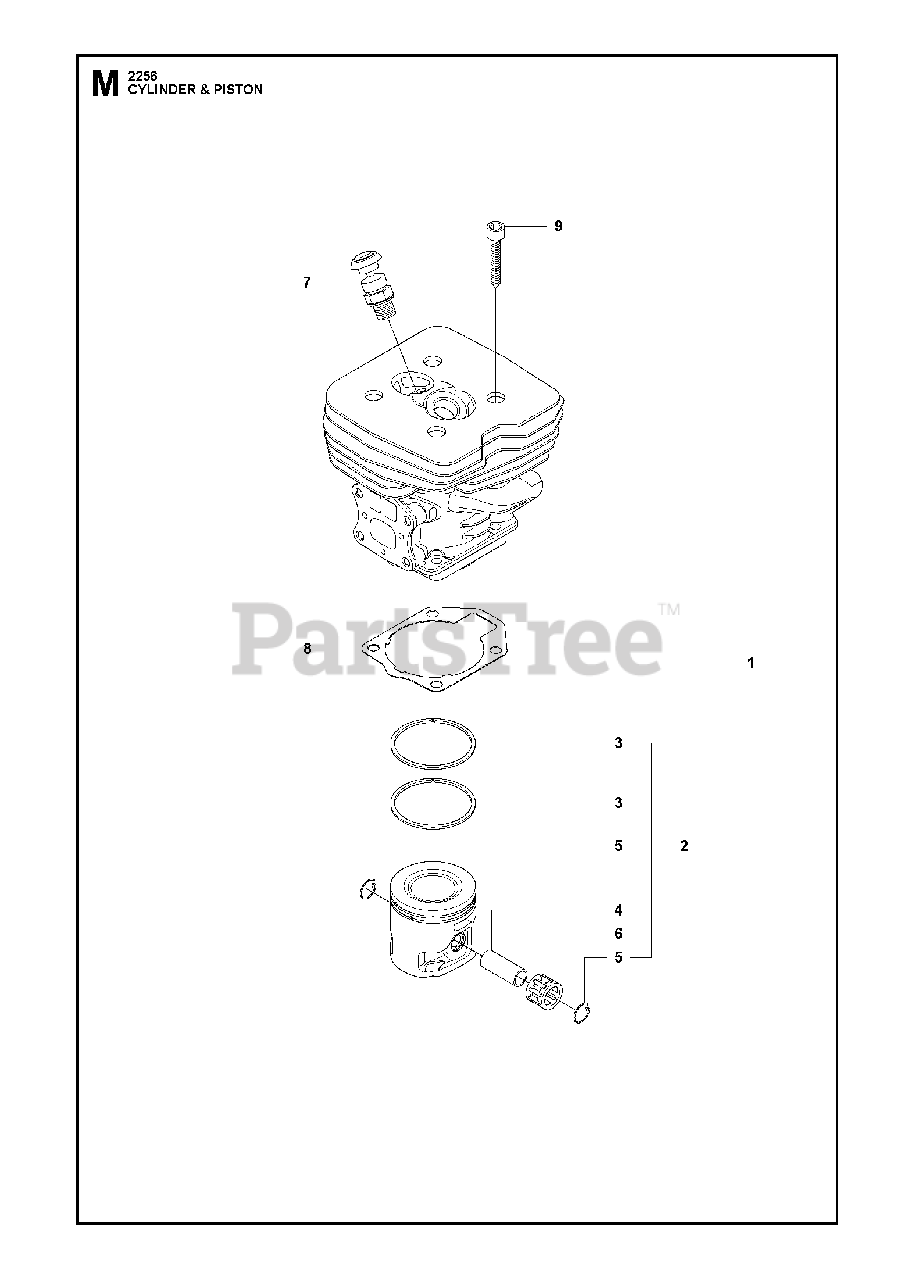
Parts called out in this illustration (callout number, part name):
1	CYLINDER ASSY
2	PISTON ASSY
6	RP SUPPORT BUSHING
7	DECOMPRESSION VALVE
9	SCREW MC6S 5X25
